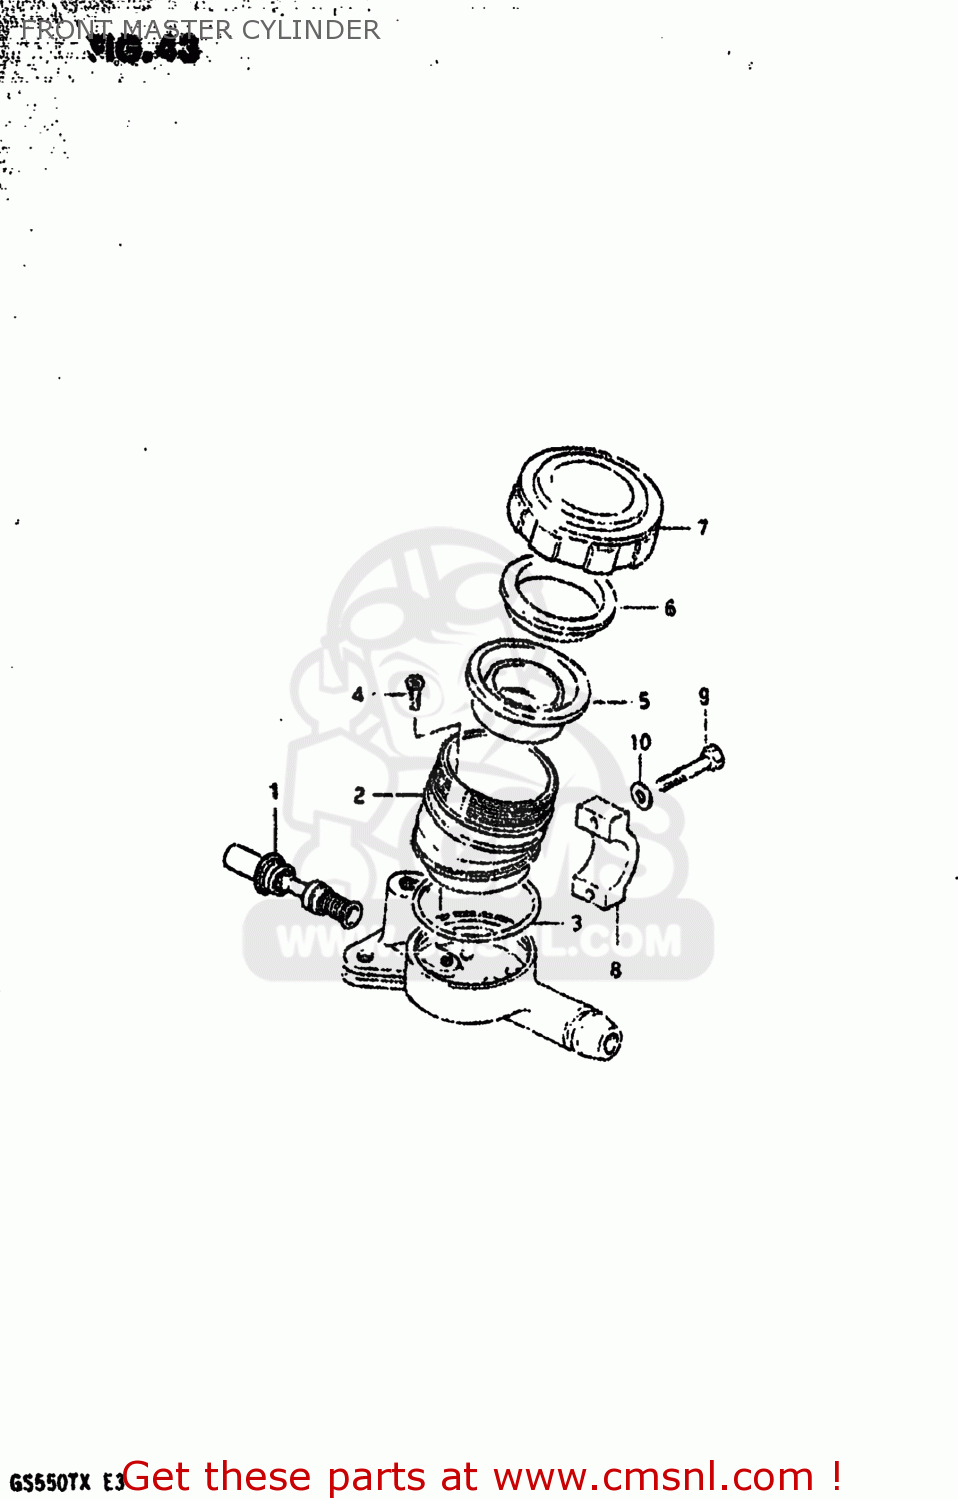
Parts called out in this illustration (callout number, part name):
1	PISTON & CUP SET
2	RESERVOIR
3	O RING
4	SCREW,MASTER CYLINDER
5	DIAPHRAGM
6	PLATE
7	CAP,MASTER CYLINDER,REAR
8	HOLDER,MASTER CYLINDER
9	BOLT
10	WASHER
